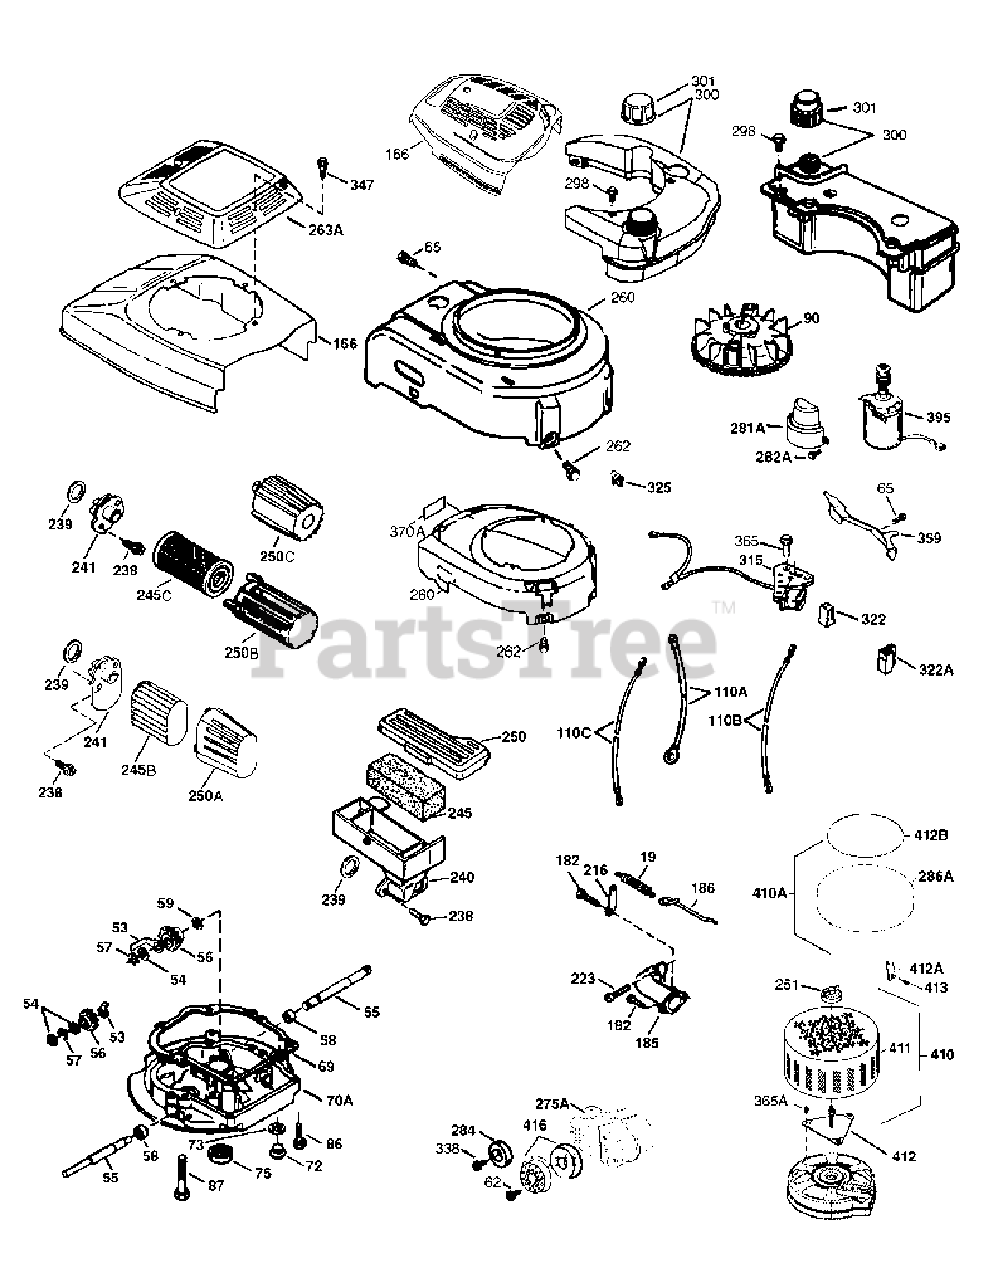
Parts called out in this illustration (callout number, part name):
19	Extension Spring
65	Screw, 10-24 x 9/16"
69	Flange Gasket (With Silicon Bead)
72	Oil Drain Plug (Flush Mount)
86	Screw, 1/4-20 x 1-1/4"
110A	Ground Wire
130B	Screw, 1/4-20 x 1/2"
166	Engine Shroud (Beige)
182	Screw, 1/4-28 x 7/8"
185	Intake Pipe
186	Governor Link
223	Screw, 1/4-20 x 1"
238	Screw, 10-32 x 49/64"
239	Air Cleaner Gasket
241	Air Cleaner Collar
245B	Air Filter (Paper)
250B	Air Cleaner Cover
260	Blower Housing
262	Screw, 1/4-20 x 1/2"
300	Fuel Tank (Natural Incl. 292 & 301)
301	Fuel Cap (Black)(1-1/2" I.D.)
347	Screw, 10-32 x
355	Starter Handle (standard)
999	Summer Maintenance Kit
